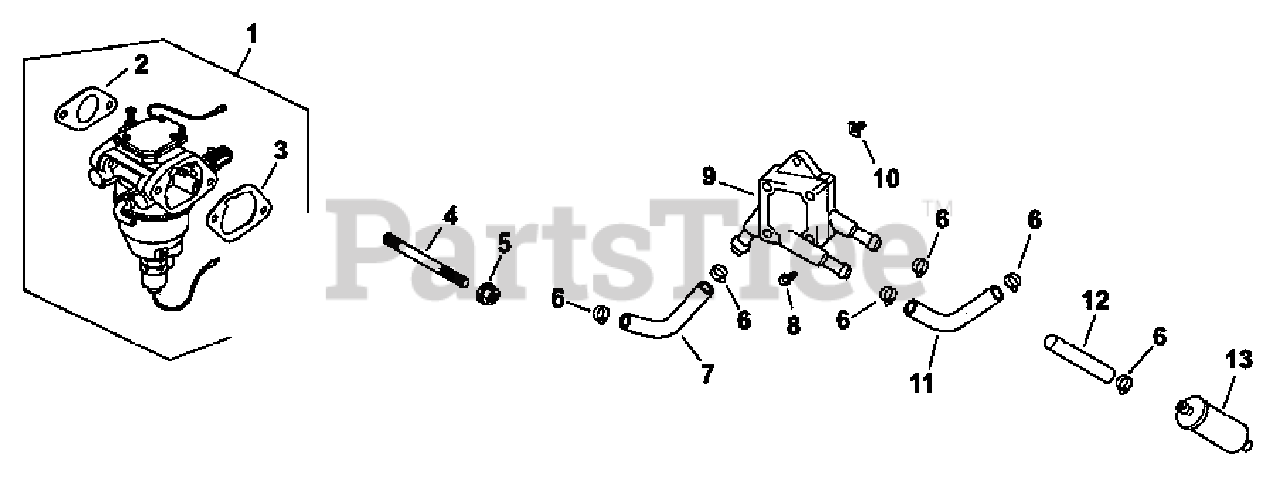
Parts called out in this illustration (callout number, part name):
1	Carburetor w/Gaskets
2	Carburetor Gasket
3	Air Cleaner Base Gasket
4	Intake Manifold Stud
5	Hex Flange Nut (M6 x 1.0)
6	Hose Clamp
7	Fuel Line (3-1/2")
8	Hex Cap Screw (M6 x 1.7 x 18)
10	Plastic Nut
11	Fuel Line (10-1/2")
12	Fuel Line (3-1/2")
13	Fuel Filter
